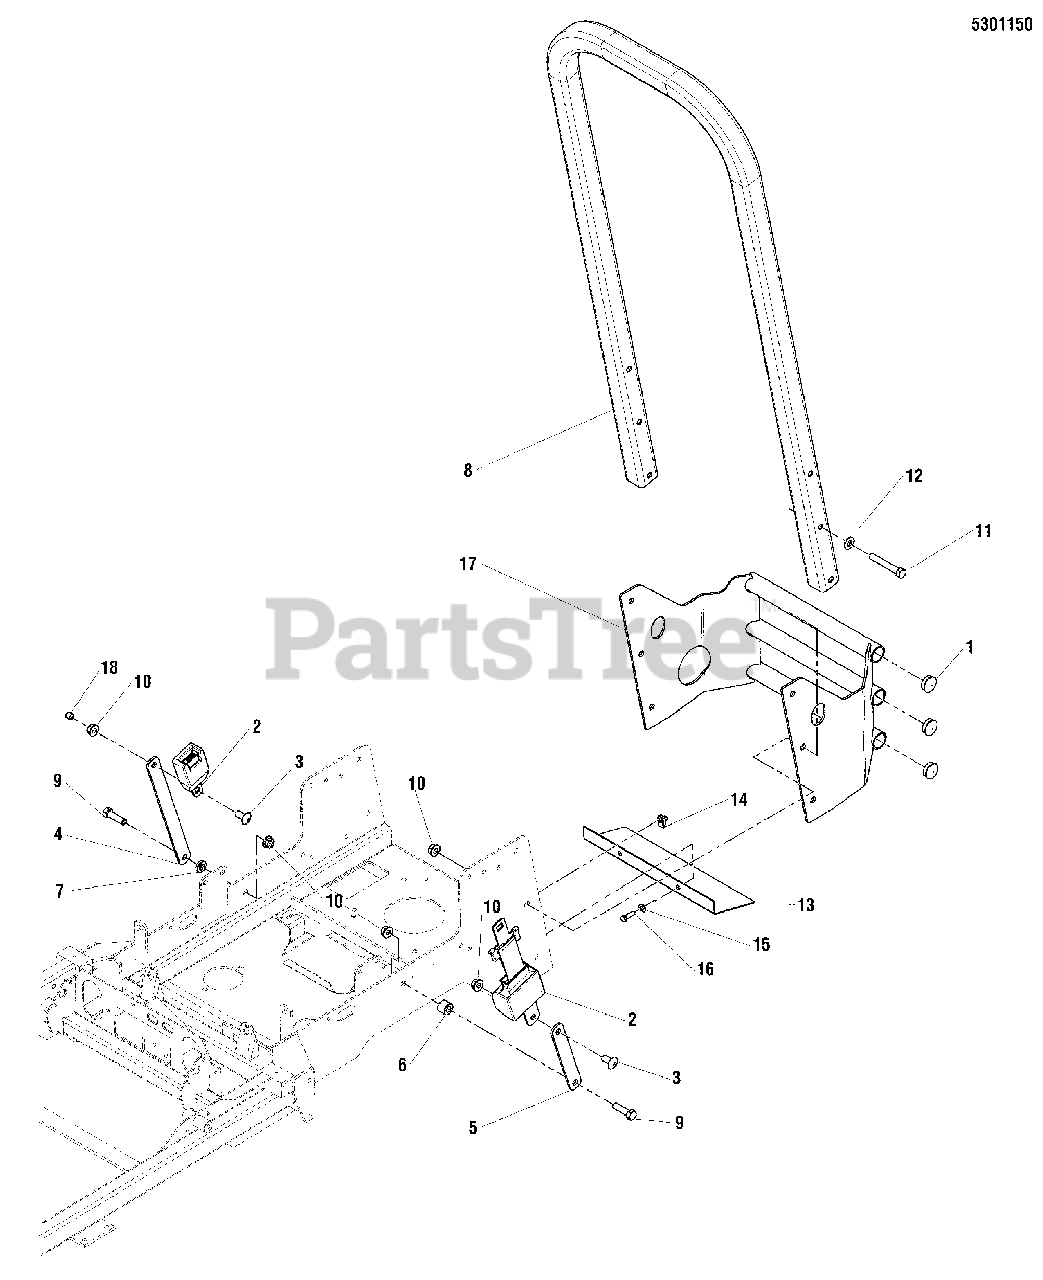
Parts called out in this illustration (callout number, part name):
1	PLUG, PANEL, 1.25 - BLACK
2	SEAT BELT, RETRACTING - ASSM
3	SCREW, 1/2-13 X 1.00, SHCS
4	MOUNT, SEAT BELT - RH - BLK
5	PLATE, SEAT BELT ANCHOR - BLK
6	SPACER, .52 X 1.00 X .75
7	SPACER, .515 X 1.00 X .218
8	ROPS (Call 1-800-933-6175 x708 if replacing a ROPS)
9	BOLT, 1/2-13 X 1-3/4" GD5 YZ
10	NUT, 1/2-13 HEX NYLOCK FLANGE
11	BOLT, 1/2-13 X 3-1/4, HEX HD, GD5, YZ
12	WASHER, 1/2 SAE
13	PLATE, HEAT SHIELD - BLK
14	BODY CLIP, 5/16-18 X 1/2 DEEP
15	WASHER, 5/16 SAE
16	BOLT, 5/16-18 X 1 GD5 YZ
17	WELD, BUMPER - IS500Z - ORG
18	CAP, VINYL - .750 X .50 - BLK
18	WELD, BUMPER, IS500Z - ORG
